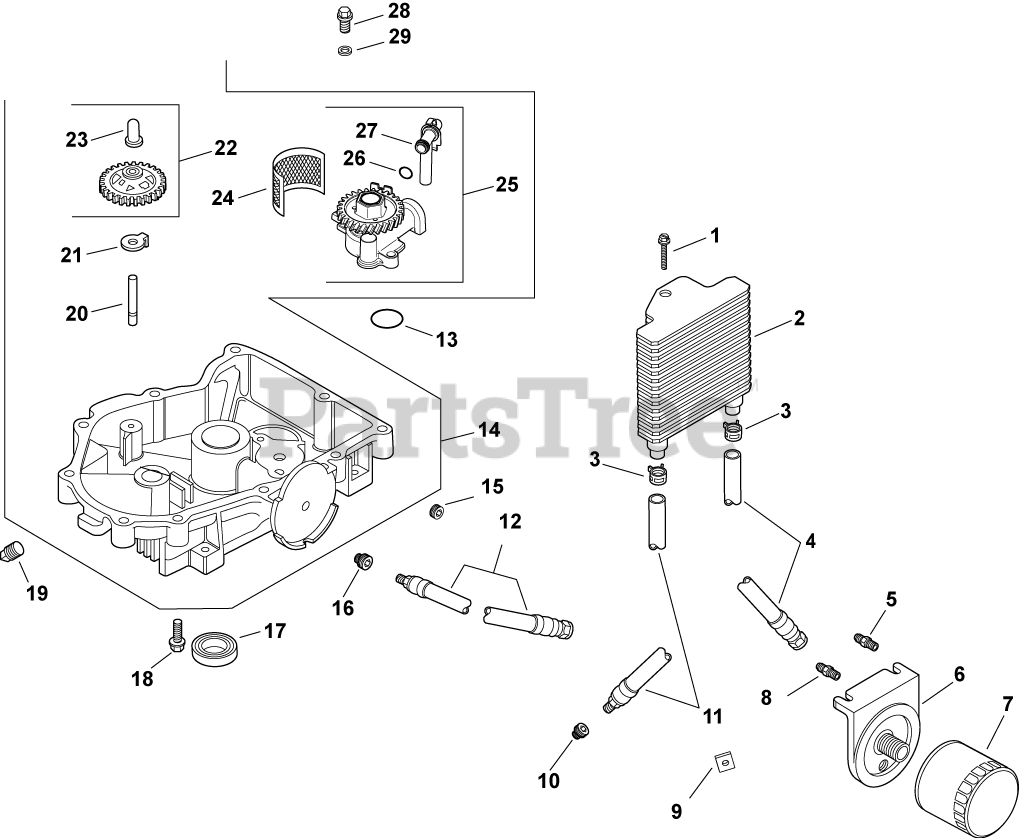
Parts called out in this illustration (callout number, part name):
1	SCREW, TAP M6X1.7X18
2	COOLER, OIL
3	CLAMP, OIL COOLER HOSE-USE 25 237 31-S
4	HOSE, OIL
7	OIL FILTER
8	CONNECTOR
9	NUT, PLASTIC (KM)-USE 25 100 37-S
10	BUSHING, REDUCING
11	HOSE, OIL
14	OIL PAN ASSEMBLY - USE 24 199 32-S
15	PLUG, PIPE CTSK 3/8"
16	BUSHING, REDUCING
17	SEAL, OIL (KM)-USE 25 032 06-S
18	SCREW, FLG M8X1.25X45
19	PLUG, SQ HD PIPE 3/8"
20	SHAFT, GOVERNOR GEAR
21	TAB, LOCKING
22	KIT, GOVERNOR GEAR W/PIN
23	PIN, GOVERNOR REGULATING
24	SCREEN, OIL
25	PUMP ASSEMBLY, OIL-USE 24 393 53-S
26	O-RING, OIL PICK-UP
27	KIT, OIL PICK-UP TUBE
28	SCREW,FLG THD FRM M6X1.0X25-(#25086395S)
29	WASHER, FLAT 6 MM
